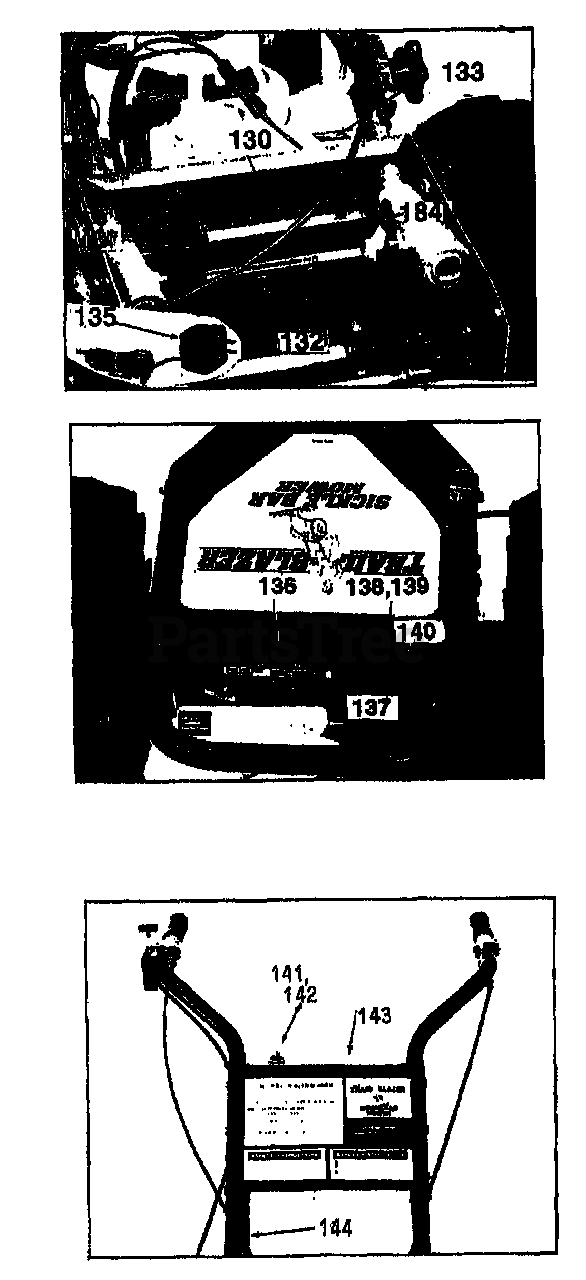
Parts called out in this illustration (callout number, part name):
130	Battery, with leads
132	Bolt, 6MMx110MM, Class 8.8 (2 required)
133	Decal, Battery Charging Instructions
135	Charger, Battery
136	Decal, Battery Short Circuit Caution
137	Locknut, 6MM Nylon (2 required)
138	Bolt, 5MM, Attaches Battery Clamp to Rear Frame Hood (2 required)
139	Lockwasher, 5MM (2 required)
140	Clamp, Battery Cable
141	Keyswitch-
142	Keys, One Pair
143	Decal, Electric Start Control Panel
144	Wiring Harness, Keyswitch to Battery
